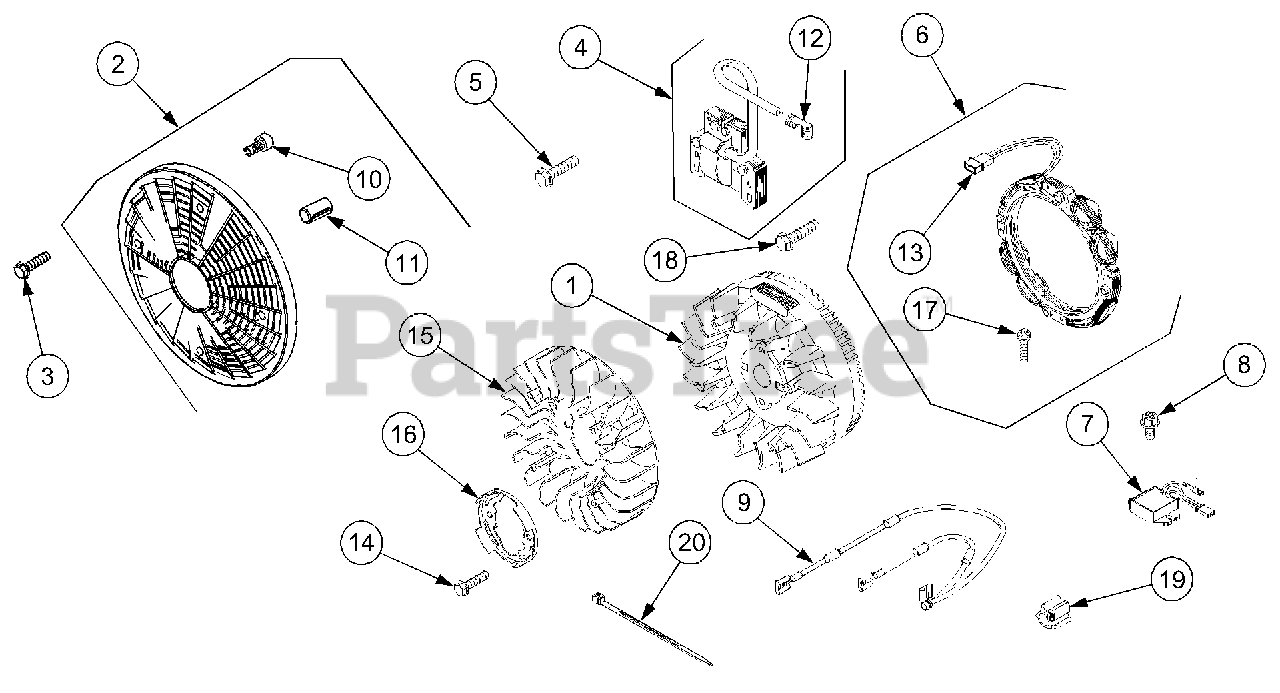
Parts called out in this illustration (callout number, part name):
1	Flywheel & Ring Gear
2	Screen, Rotating
3	Screw, Rotating Screen
4	Armature, Magneto
5	Screw, Magneto Armature
6	Alternator
7	Regulator
8	Screw, Regulator
9	Wire Assembly
12	Termainl, Spark Plug
13	Wire/Connector, Alternator
14	Screw, Fan Retainer
15	Fan, Flywheel
16	Retainer, Fan
17	Kit, Screw/Washer
18	Screw, Alternator
20	Tie, Cable
